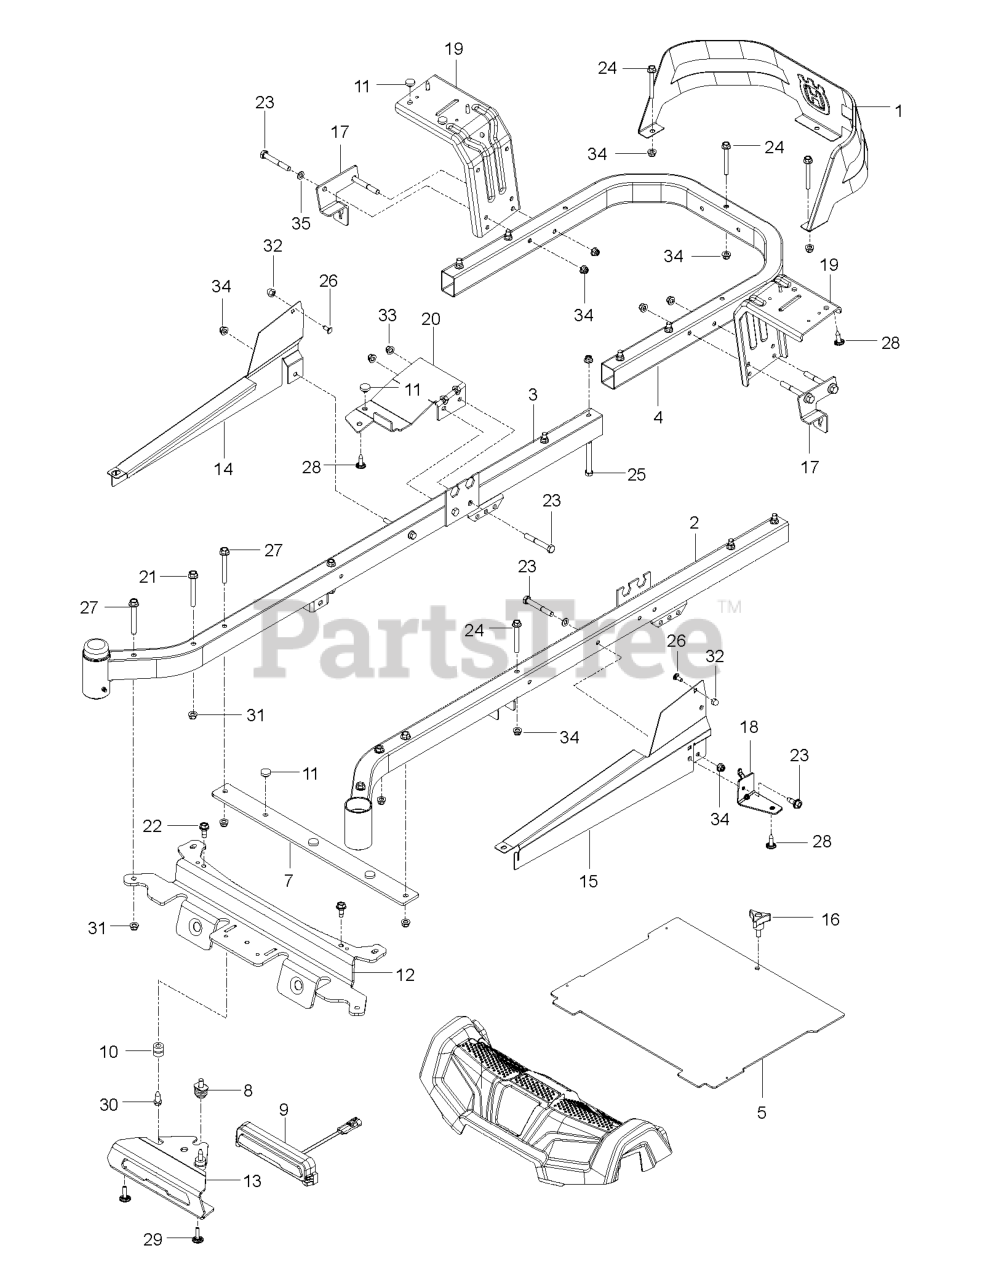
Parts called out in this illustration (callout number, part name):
1	GUARD.ENGINE.HUSQ.RZ.X498
2	FRAME.TUBE.RZ.MAIN.WELD.RH.ORG
3	FRAME.TUBE.RZ.MAIN.WELD.LH.ORG
4	TUBE.PNT.FRAME.RER.HUSQ.23".RZ
5	PLATE, FOOT W/DECALS RZ
6	COVER.FOOTREST.REFRESH.ASM
7	FOOTREST.PLATE.SUPPORT.X431
8	SCREW.ADJ.ISOLATOR.BOLT.ASSY
9	LIGHT.ZTR.LED.ASM
10	GROMMET.RUBBER.PUSHIN
11	GROMMET.BUMPER
12	CROSS.PNT.MEMBER.BLK
13	BRACKET.SKIDPLTE.LED.RFRSHX417
14	COVER.RAIL.RH.RZ.X668
15	COVER.RAIL.LH.RZ.X668
16	KNOB W/STUD
17	BRKT ROD.BYPASS.EZT.X431
18	SUPPORT.PNT.LH.CONSOLE.FRONT
19	FENDER.SUPPORT.PNT.X431
20	SUPPORT.PNT.RH.CONSOLE.FRONT
21	BOLT SHOULDER,FLANGED,3/8-16X3
22	BOLT.5/16-18.THRD.ROLL.SHOULDR
23	BOLT.FIN HEX 5/16-18UNC X2 1/4
24	BOLT HEX
25	BOLT.HEX.FIN.3/8-16 X 3.GR5
26	BOLT.CARRIAGE.5/16-18.7/16
27	HHFS 3/8-16 X 3 GRD 5 ZD
28	SCREW.#10 X 0.750.BOS
29	SCREW.#10 X 0.500
30	BOLT.5/16-18X1.25
31	NUT 3/8-16 HEX FLG NYLOC ZD
32	NUT ACORN,FLANGED,5/16-18
33	NUT LOCK HEX FLANGE 5/16-18
34	5/16-18 NYLOC FLANGE NUT
35	WASHER
